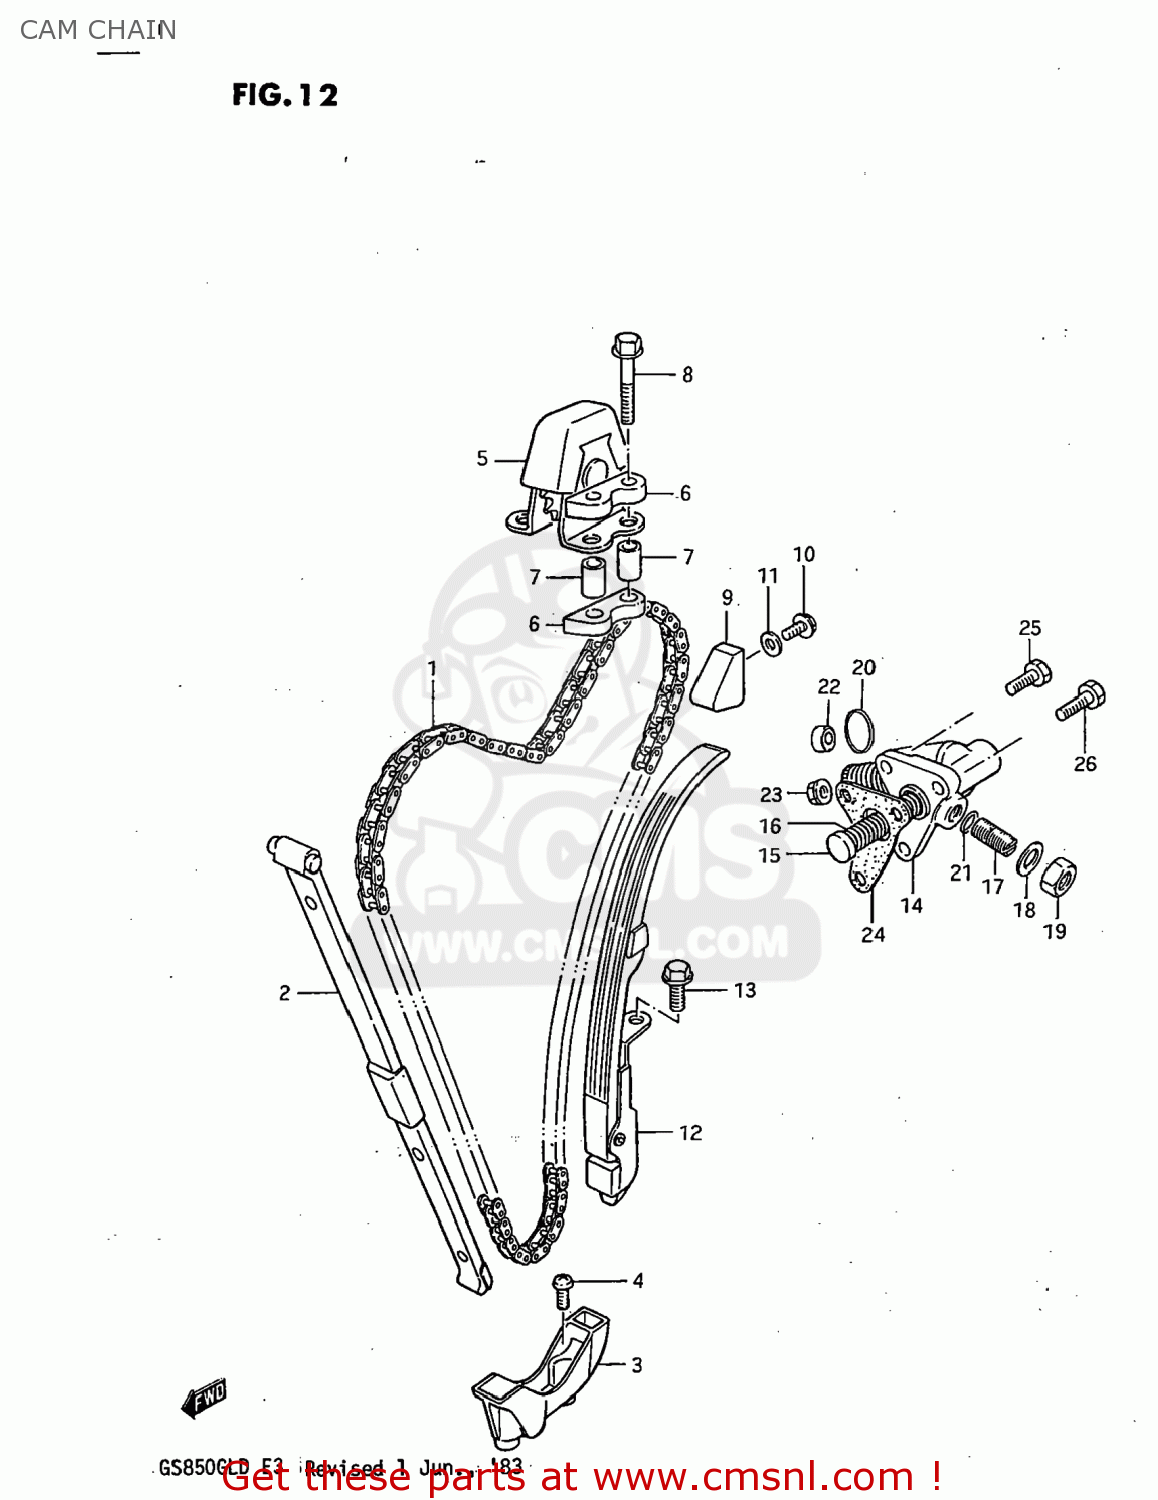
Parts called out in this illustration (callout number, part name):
1	CHAIN,CAMSHAFT DRIVE(120L)
2	GUIDE,CAM CHAIN NO.1
3	HOLDER,CAM CHAIN GUIDE
4	SCREW
5	IDLER,CAM CHAIN
6	CUSHION,IDLER
7	SPACER
8	BOLT
9	GUIDE,CAM CHAIN
10	BOLT
11	GASKET (NAS)
12	TENSIONER,CAM CHAIN
13	BOLT
14	ADJUSTER ASSEMBLY,TENSIONER
15	ROD,PUSH
16	SPRING
17	SCREW
18	WASHER
19	NUT
20	O RING(D:2.4,ID:20.8)
21	O RING(D:1.9,ID:5.7)
22	SEAL,OIL(10X16X4)
23	NUT
24	GASKET,TENSIONER ADJUSTER (MCA)
25	SCREW
26	SCREW
